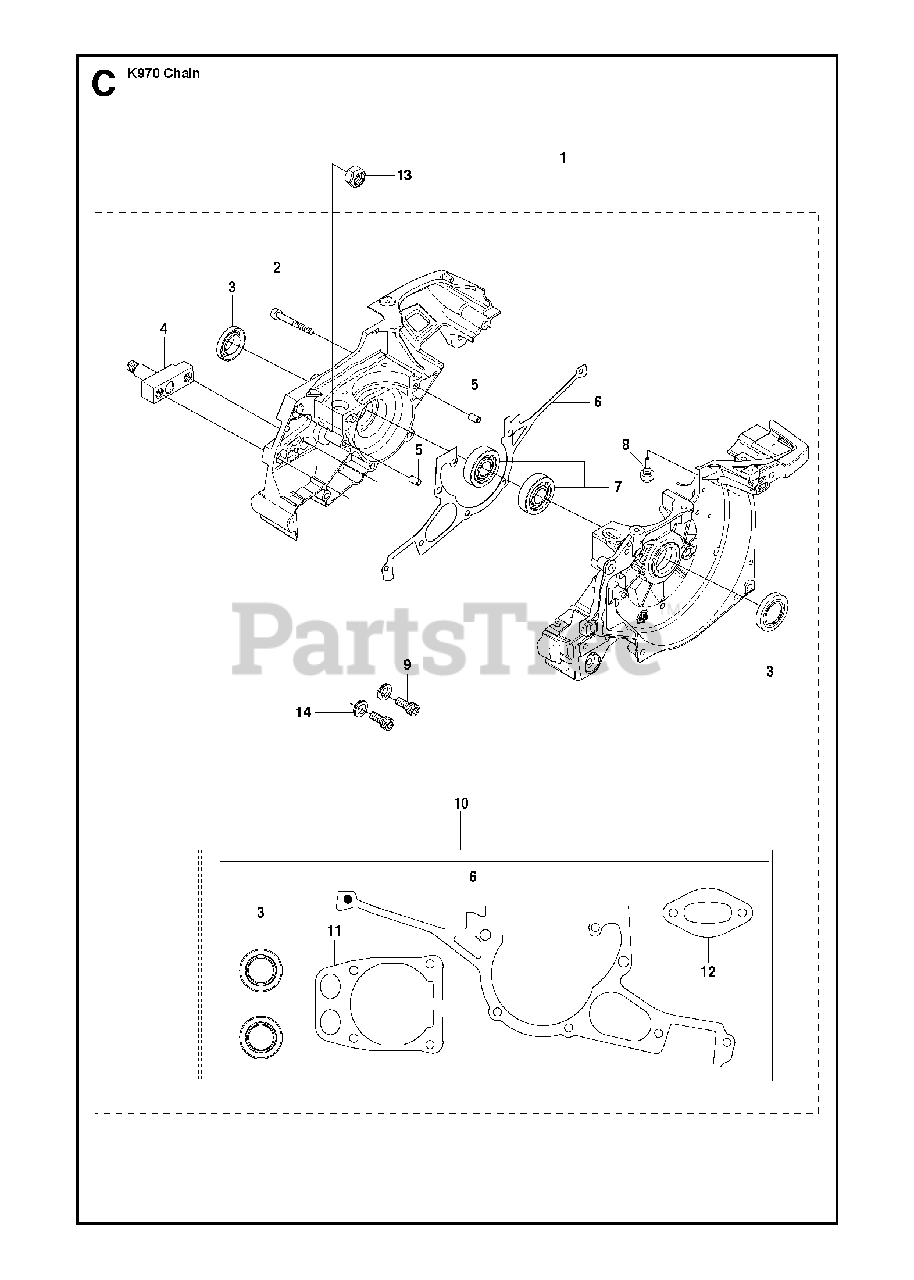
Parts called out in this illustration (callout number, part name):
1	CRANKCASE ASSYIncl. 2 - 12
2	SCREW ITXSCM
3	SEALING RING
5	GUIDE BUSHING
7	BALL BEARING
8	RUBBER BUSHING
10	GASKET KITIncl. 3 , 7, 11 - 12
12	GASKET
